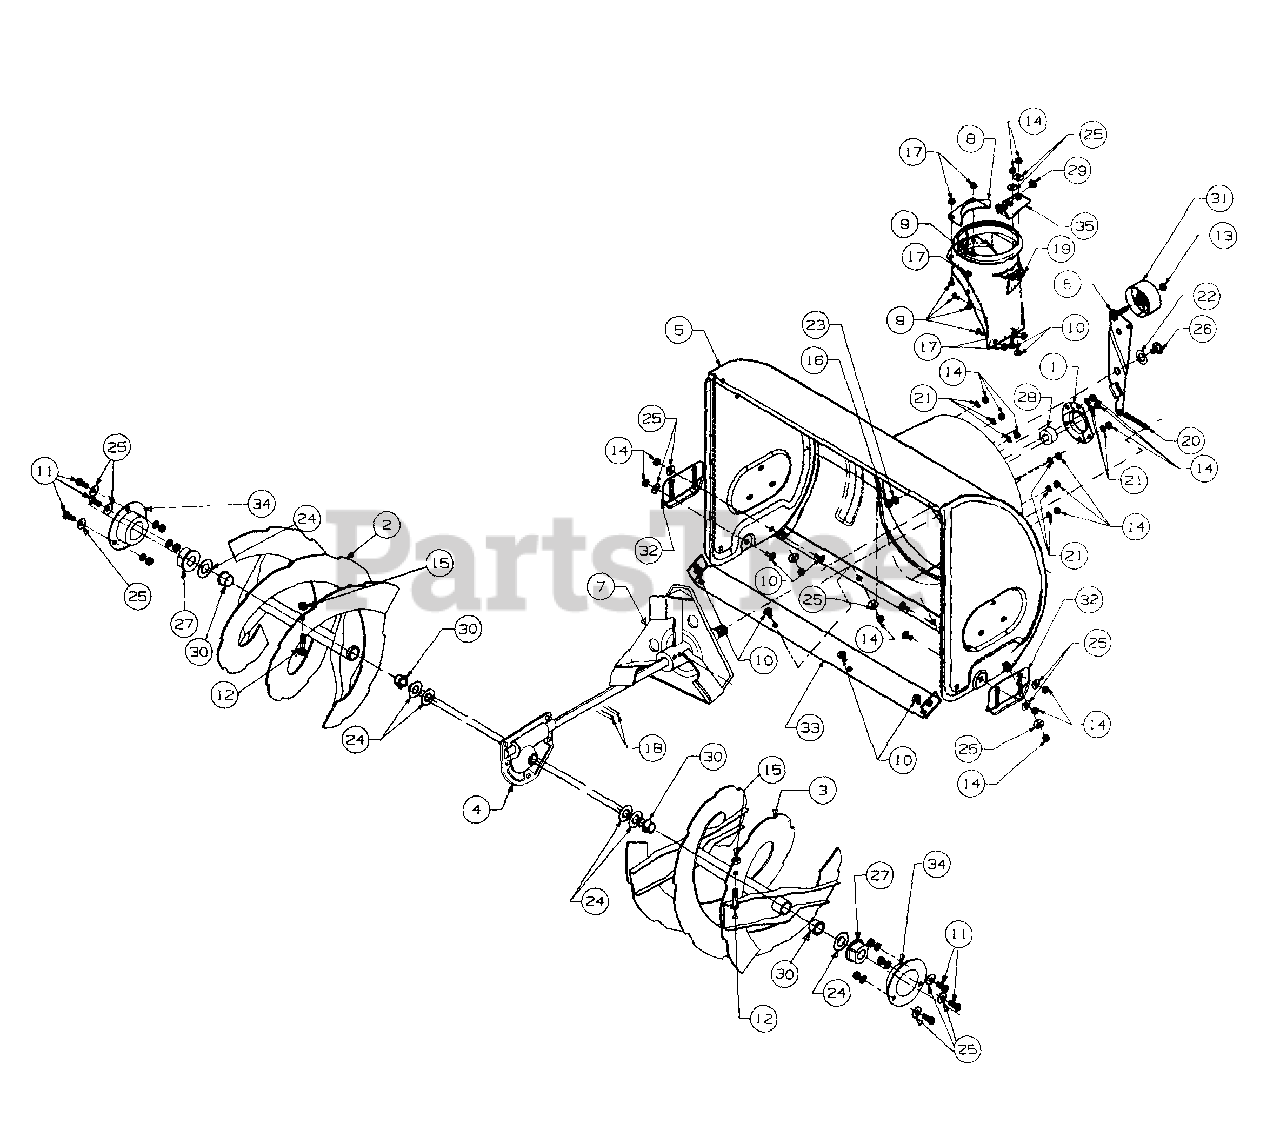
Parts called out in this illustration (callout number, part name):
1	Housing-Bearing
4	Gear Assembly 22"
9	Screw-Carriage
10	Screw-Carriage
11	Screw-Hex
12	Shear Bolt
13	Nut-Hex Lock
14	Nut-Hex
15	Nut-Hex
16	Nut-Hex
17	Nut-Hex Lock
18	Pin-Spring
19	Adapter-Chute
20	Spring
21	Washer-Lock
22	Washer-Flat
23	Washer-Lock
24	Washer-Flat
25	Washer-Bell
26	Screw-Shoulder
27	Bearing-Flange
28	Bearing-Ball
29	Bushing-Plastic
30	Bushing-Flange
31	Idler-Flat
